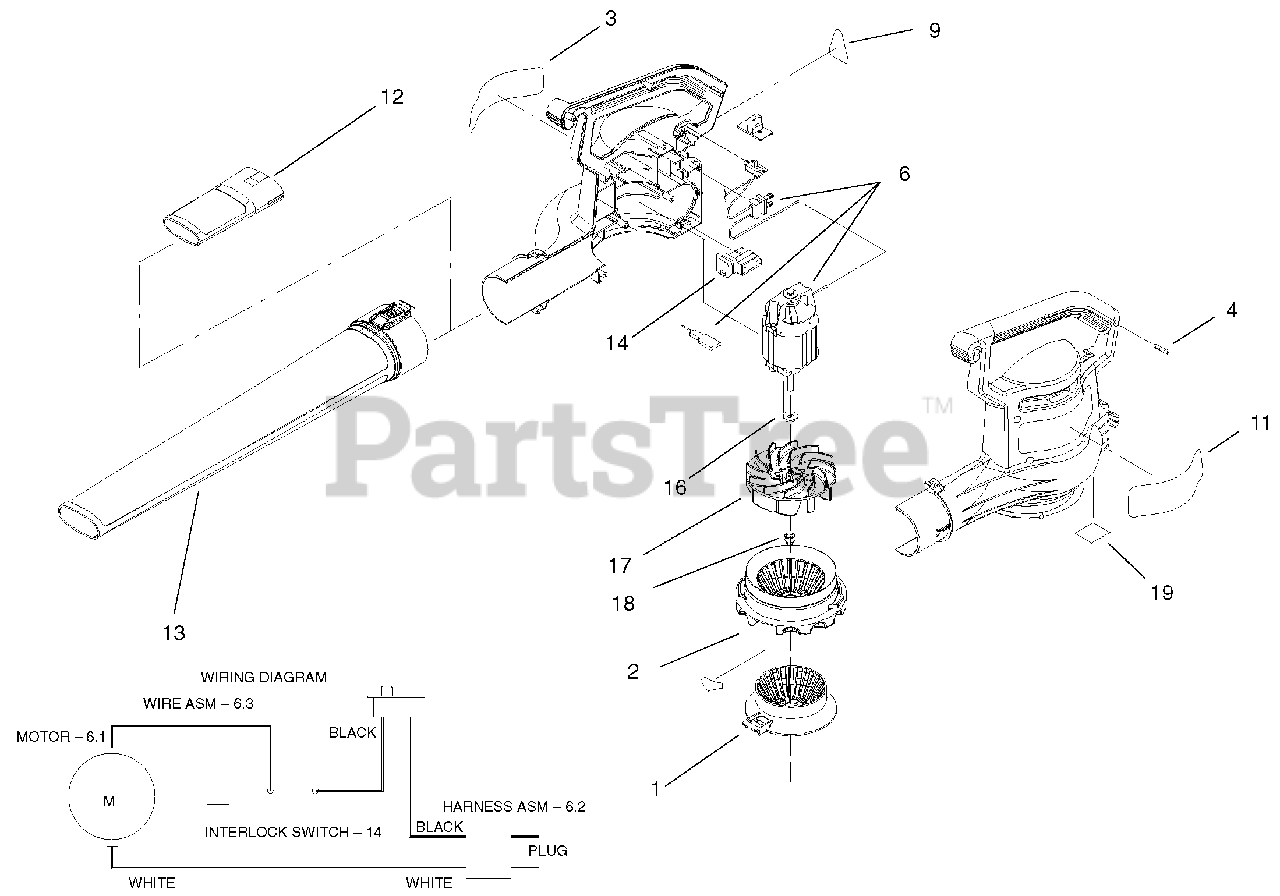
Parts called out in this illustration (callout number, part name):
1	Choke-Air, Red
2	ASM-Inlet Cover & Decal
3	Decal-Warning
4	Screw-PPH
6	ASM-Motor & Harness
9	Decal-Information
11	Decal, Logo, Suprblwr
12	Insert-Tube
13	Tube-Blower
14	Switch-Interlock
17	Impeller-Blower
18	Nut-Hex
